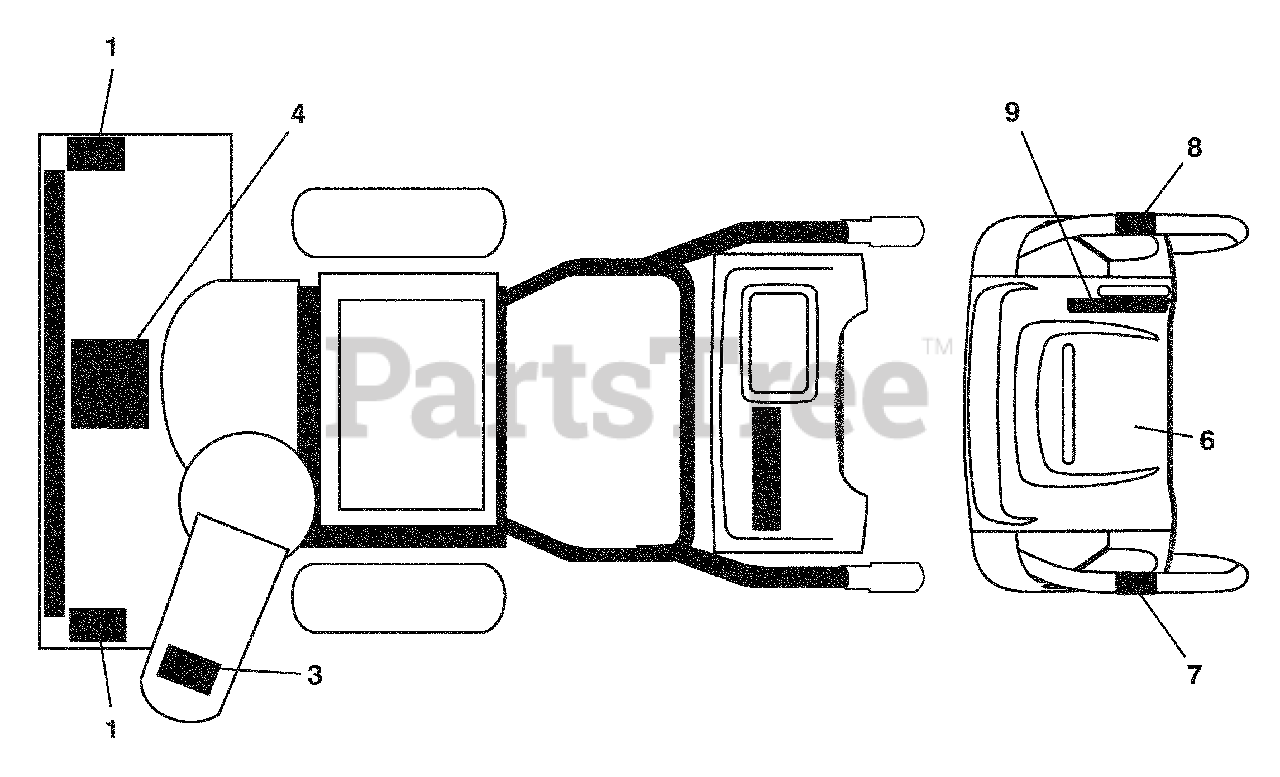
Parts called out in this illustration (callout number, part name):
1	DECAL, DANGER
3	DECAL, DANGER, DEFLECTOR
4	DECAL, DANGER
6	DECAL, INSTRUCTION
7	DECAL, TRACTION LEVER
8	DECAL, AUGER LEVER
9	DECAL, SPEED CONTROL
